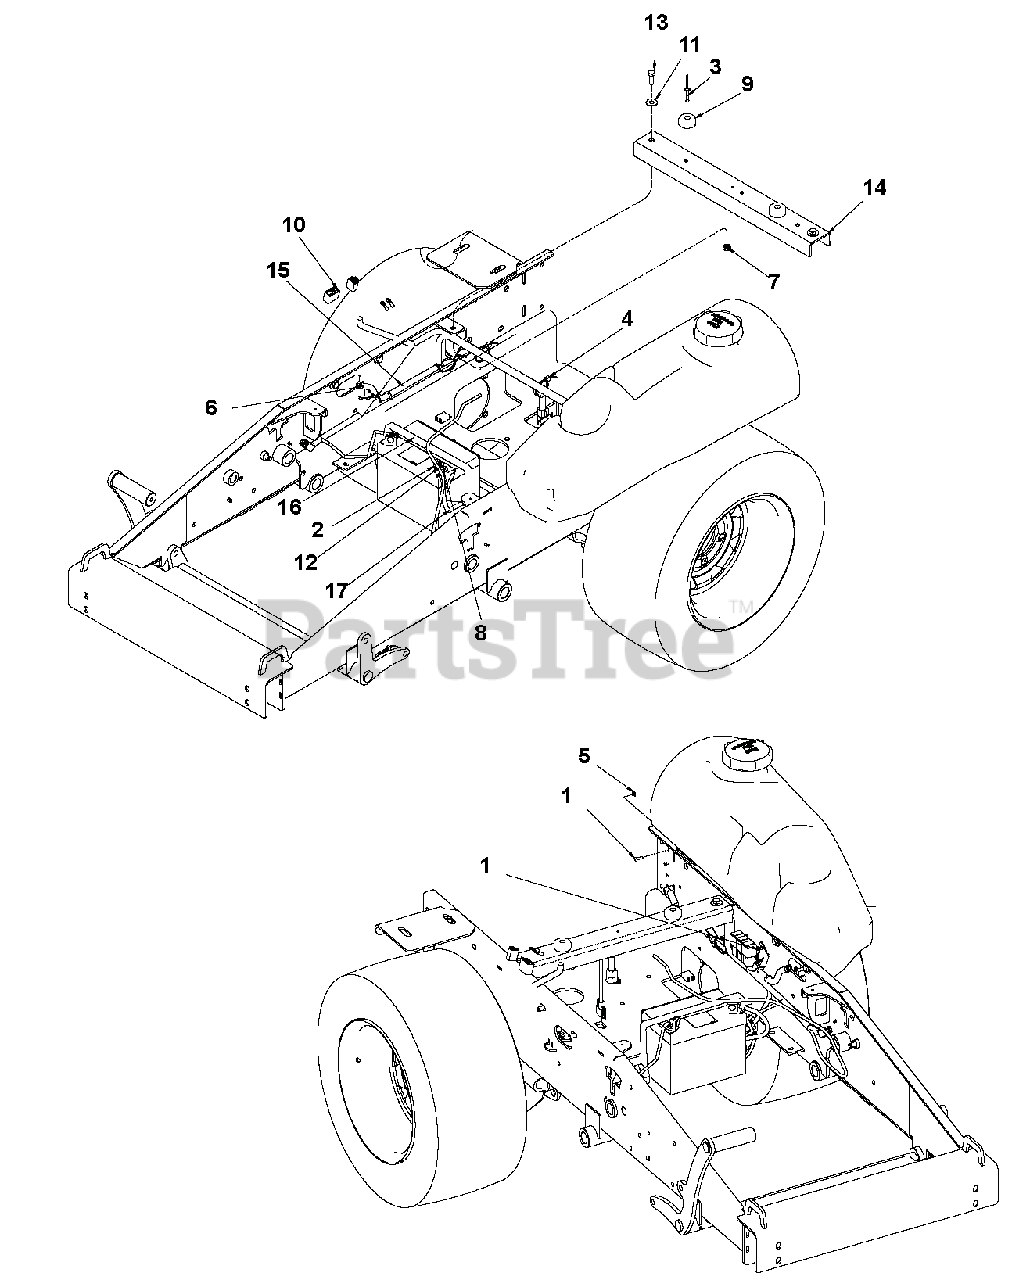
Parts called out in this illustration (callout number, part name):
1	SCR-MCH 10-24X.62 P/HD
2	BOLT, 5/16-18X.750 CRG 5 Y
3	RIVET, 3/16 X .500 POP ST
4	TIE WRAP, BLACK LG 7.31
5	NUT, 10-24 KEPS Y
6	CLAMP, HOSE - 1/2" SPRING
7	NUT, .38-16 LOW CROWN LK ACORN
8	NUT, 5/16-18 STD HEX GR5 Y
9	BUMPER, RUBBER .625 X 1.50 DIA
10	HARNESS, POWER UNIT WIRE
11	@WSHR-FL-STL.438X1.00X.083 YWZ
12	WASHER, .313 MED SPRG LOCK Y
13	@BLT-HEX .38-16X1.00 GR5 YWZC
14	PLATE, TOP CROSSMEMBER
15	ASSY, FUEL LINE W/CHECKVALVES
16	BAND 15"
17	CABLE, BATTERY - 35" POSITIVE
